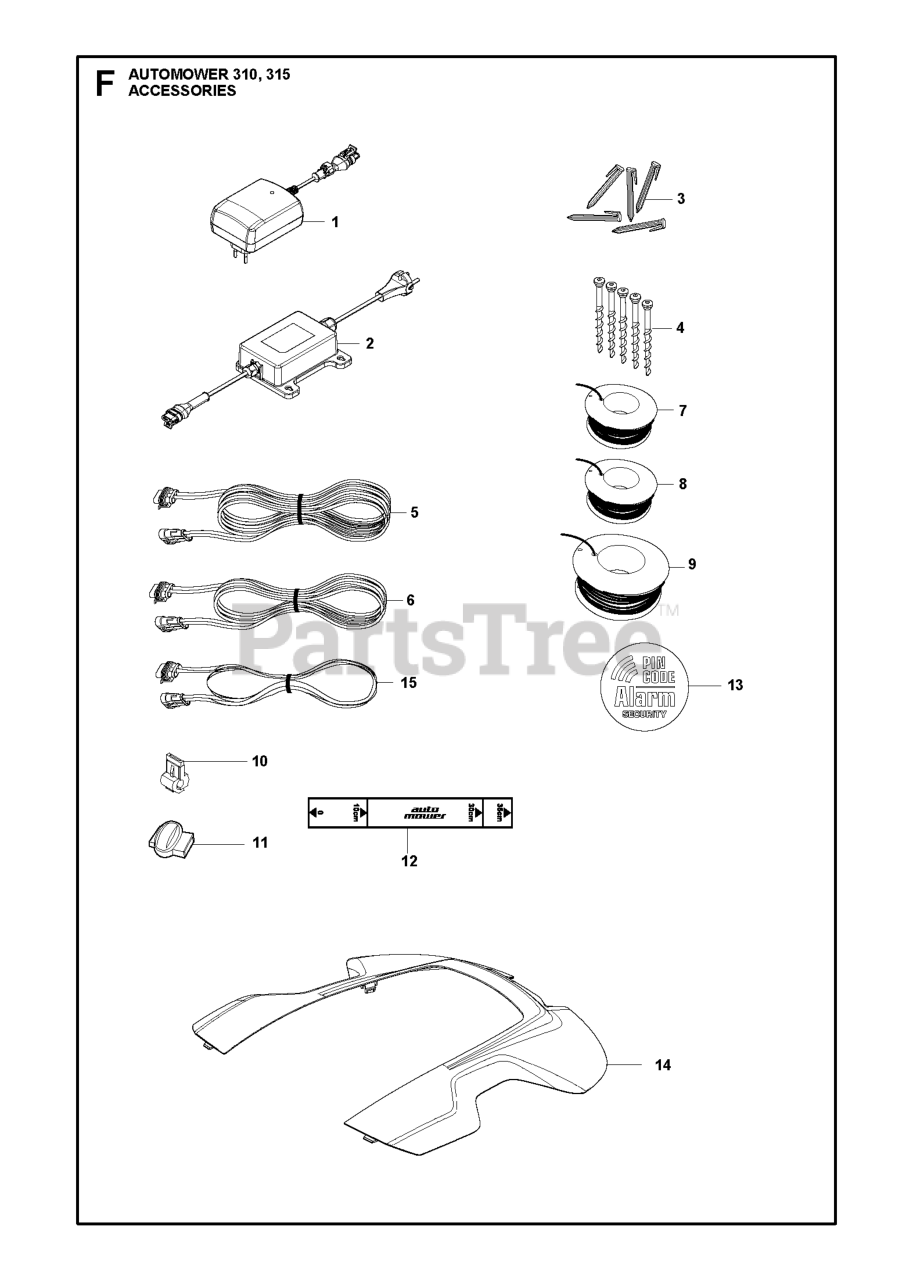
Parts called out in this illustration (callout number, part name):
1	POWER UNIT POWER SUPPLY 1,3A
3	STAPLE 100 PCS
4	SCREW KIT ANCHOR SCREW 5 PCS
5	LOOM LOW VOLTAGE CABLE 20 METE
6	LOOM LOW VOLTAGE CABLE 10 METE
7	WIRE BOUNDARY 150M
7	WIRE 150M, BLISTER
8	WIRE 250M
9	WIRE 500M
10	CONNECTOR 5 PCS, BLISTER
10	BRAKER
11	COUPLER SPLICER, 100 PCS
11	SPLICE KIT
11	COUPLER SPLICER, 5 PCS,
12	RULER / CENTIMETERS
13	LABEL SECURITY
14	WHITE COVER
14	ORANGE COVER
14	GREY COVER
15	LOOM LOW VOLTAGE CABLE 3 METER
15	CABLE ASSY LOW VOLTAGE CABLE
